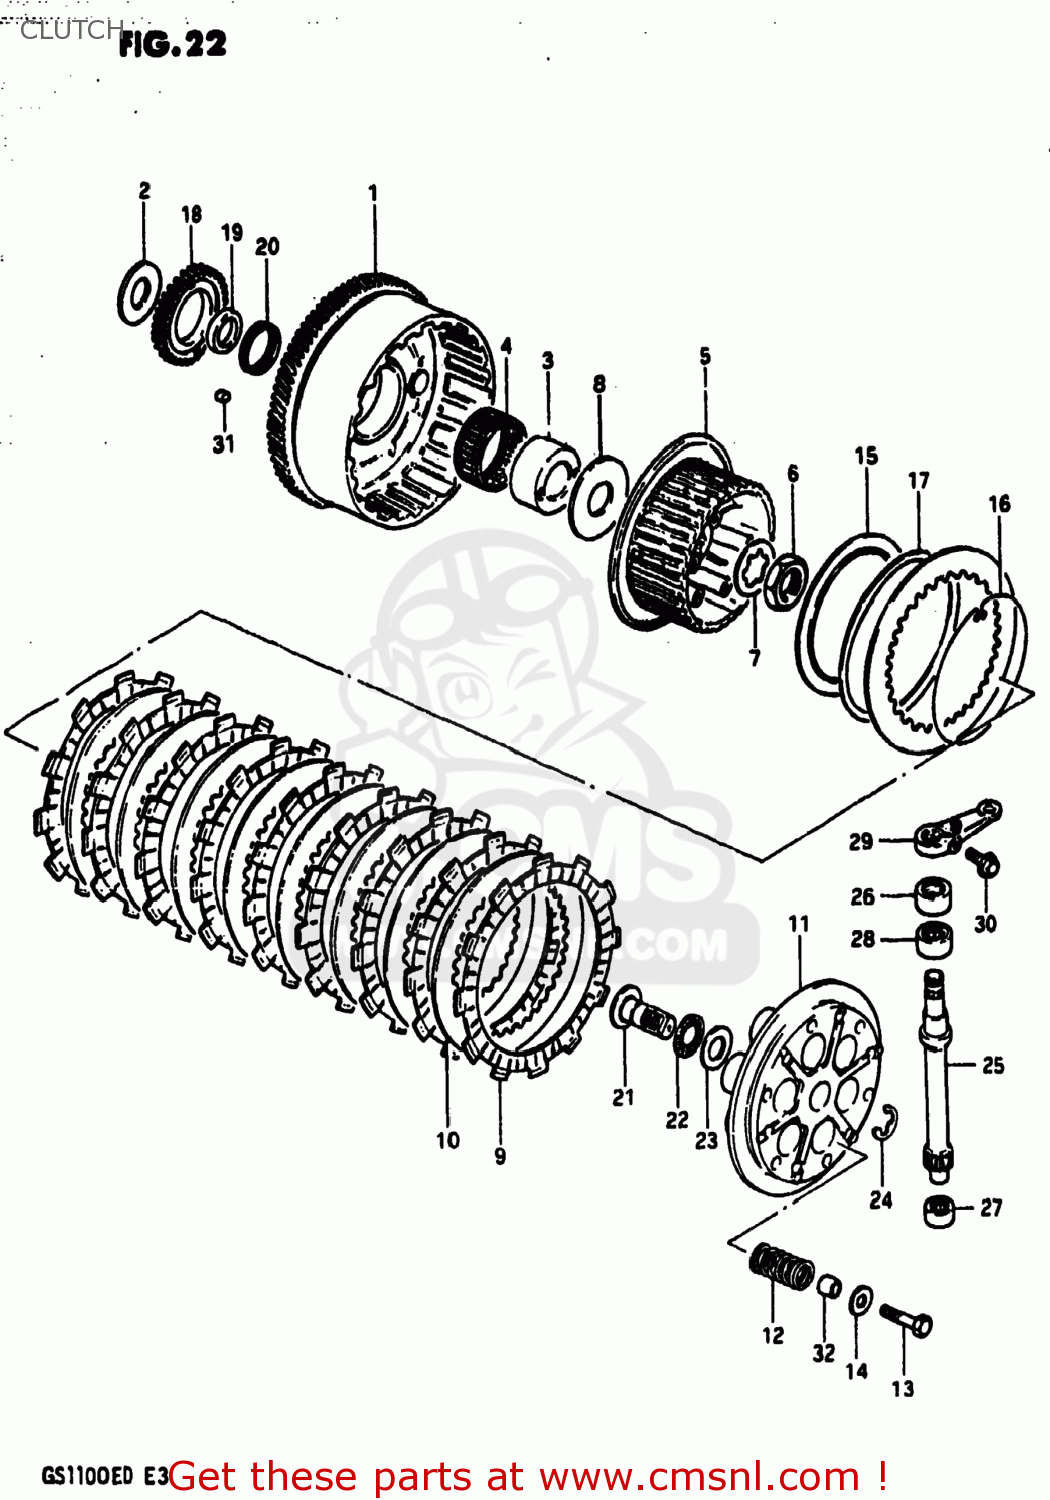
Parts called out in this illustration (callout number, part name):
1	GEAR ASSEMBLY,PRIMARY DRIVE
2	WASHER
3	SPACER
4	BEARING
5	HUB,CLUTCH SLEEVE
6	NUT
7	WASHER,LOCK
8	WASHER(25X66X3.5)
9	PLATE,CLUTCH DRIVE (MCA)
10	PLATE,CLUTCH DRIVEN (NAS)
11	DISC,CLUTCH PRESSURE
12	SPRING
13	BOLT
14	WASHER
15	SEAT,WAVE WASHER
16	RING,STOPPER
17	WASHER
18	GEAR,ENG OIL PUMP DRIVE(NT:34)
19	SPACER,OIL PUMP DRIVE GEAR
20	BEARING(36X40X10)
21	RACK,CLUTCH RELEASE
22	BEARING(15X28X2)
23	WASHER
24	E RING 12MM
25	PINION,CLUTCH RELEASE
26	OIL SEAL
27	BEARING(12X19X12)
28	BEARING(15X22X12)
29	ARM,CLUTCH RELEASE
30	BOLT (6X20)
31	CUSHION,PRIMARY DRIVEN GEAR
32	SPACER
